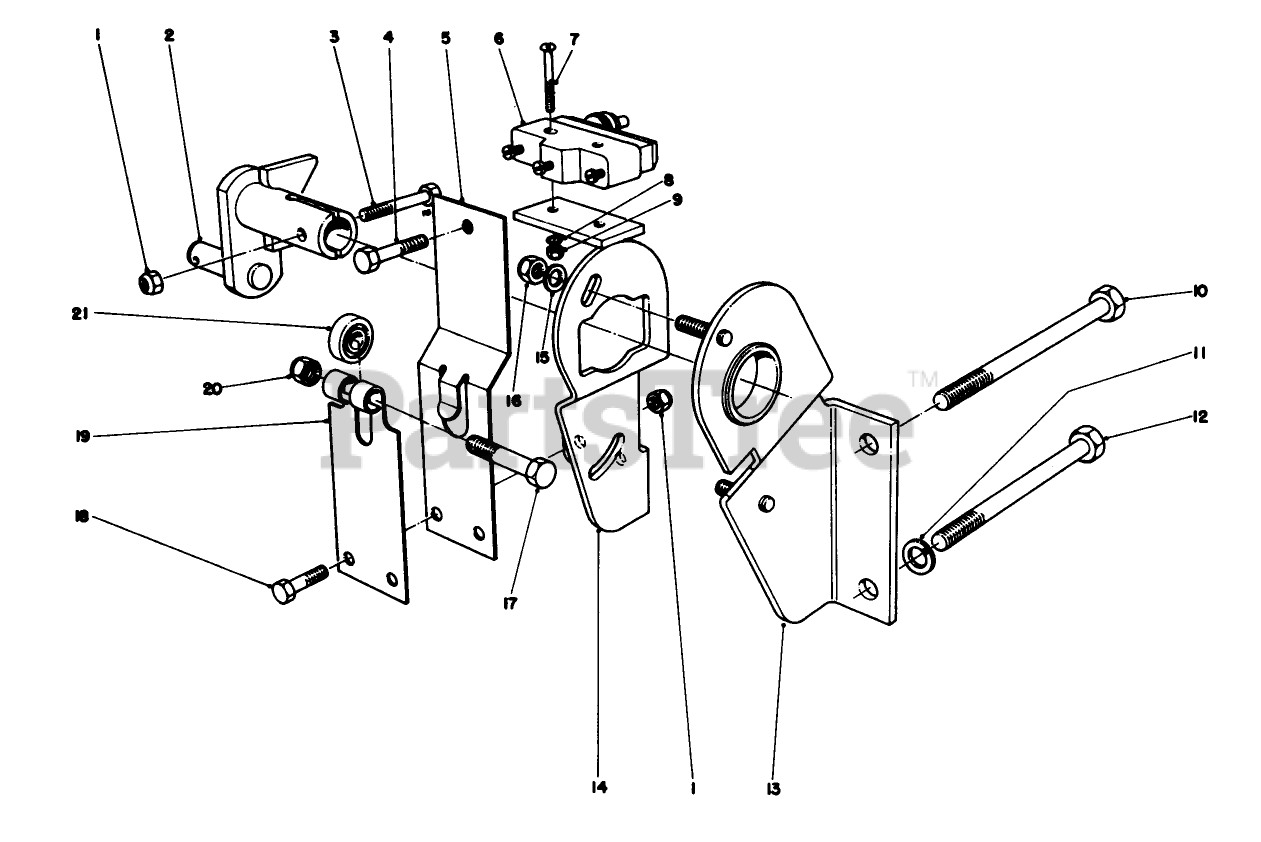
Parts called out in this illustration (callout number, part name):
1	NUT-LOCK, NI
2	Lever-Pump
3	SCREW-HH
4	SCREW-HH
5	EXTENDED LEAF SPRING ASM
6	Micro Switch
7	SCREW-MACHINE
8	WASHER-LOCK, INTERNAL
9	NUT-HEX
10	SCREW-HH
11	WASHER-LOCK
12	SCREW-HH
13	MTG BRKT WA B
14	PUMP PLATE WA B
15	Washer-Thrust
16	NUT-LOCK
17	SCREW-HH
18	SCREW-HH
19	SPRING-LEAF
20	NUT-LOCK, NI
21	BEARING-BALL
